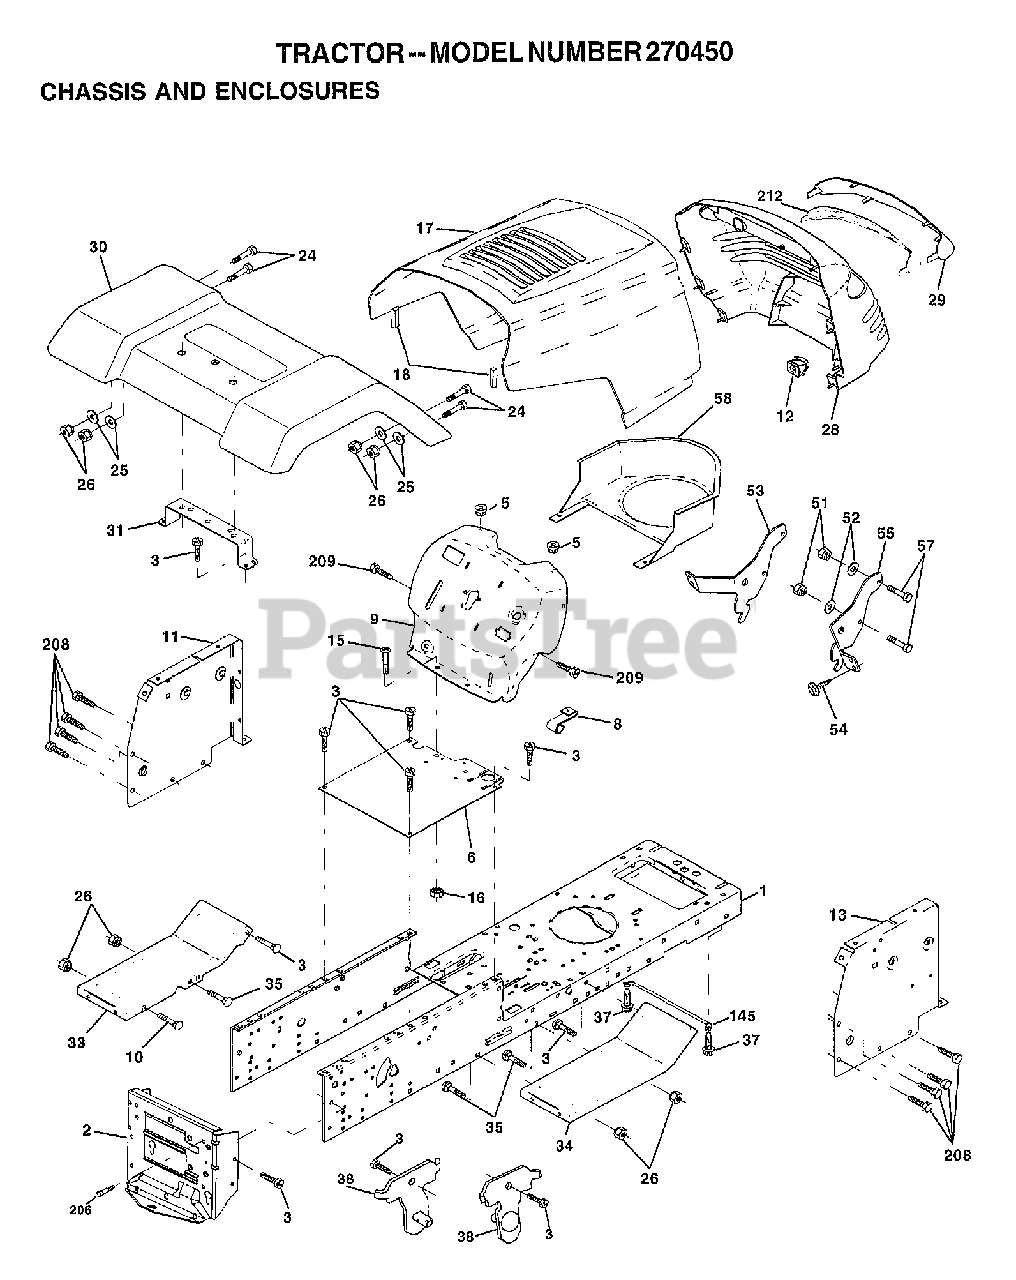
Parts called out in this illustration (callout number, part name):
2	DRAWBAR
3	SCREW
4	WASHER
5	BUMPER-HOOD/DASH
6	SADDLE-SILKSCREEN
8	CLIP.RETAINER
9	DASH
11	"PANEL-DASH,LH"
12	CLIP.TINNERMAN
14	SCREW LT
15	SCREW
16	NUT
17	HOOD ASM
24	BOLT
25	WASHER
28	GRILLE
29	LENS.GRILLE
30	FENDER
31	BRKT FENDER
33	FOOTREST.LH.PERF.
34	FOOTREST.RH.PERF
35	BOLT
37	SCREW LT
38	BRKT ASM PIVOT MOWER REAR
51	NUT
52	WASHER
53	BRACKET.GRILLE.LH
54	SCREW.HEX.WS.HD
55	BRACKET.GRILLE.RH
58	AIR DUCT
145	"ROD POVOT,CHASSIS"
206	BOLT SHOULDER
208	SCREW
209	SCREW
